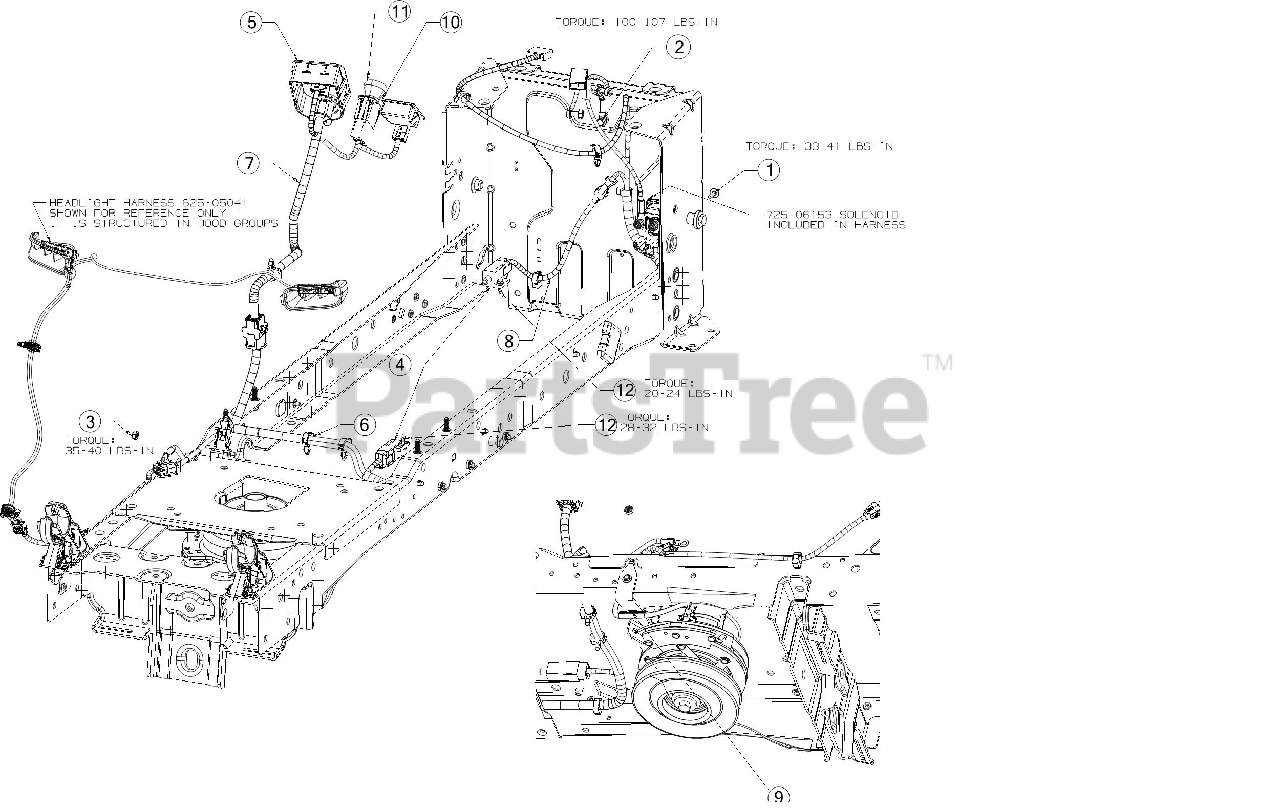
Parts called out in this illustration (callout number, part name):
1	SCREW M6-1 x .625
2	SCREW 1/4-20X.625
3	HEX NUT 1/4-20
4	INTERLOCK SWITCH (NO/NC)
5	IGNITION MODULE SWITCH RMC (ELC PTO WHTE)
6	MAIN HARNESS E-PTO/RMC/HRMTR
7	DASH HARNESS
8	REVERSE HARNESS
9	CLUTCH HARNESS 11"
10	SERVICE MINDER/HOUR METER W/BLUETOOTH
11	PTO SWITCH (YELLOW KNOB)
12	SHOULDER SCREW
